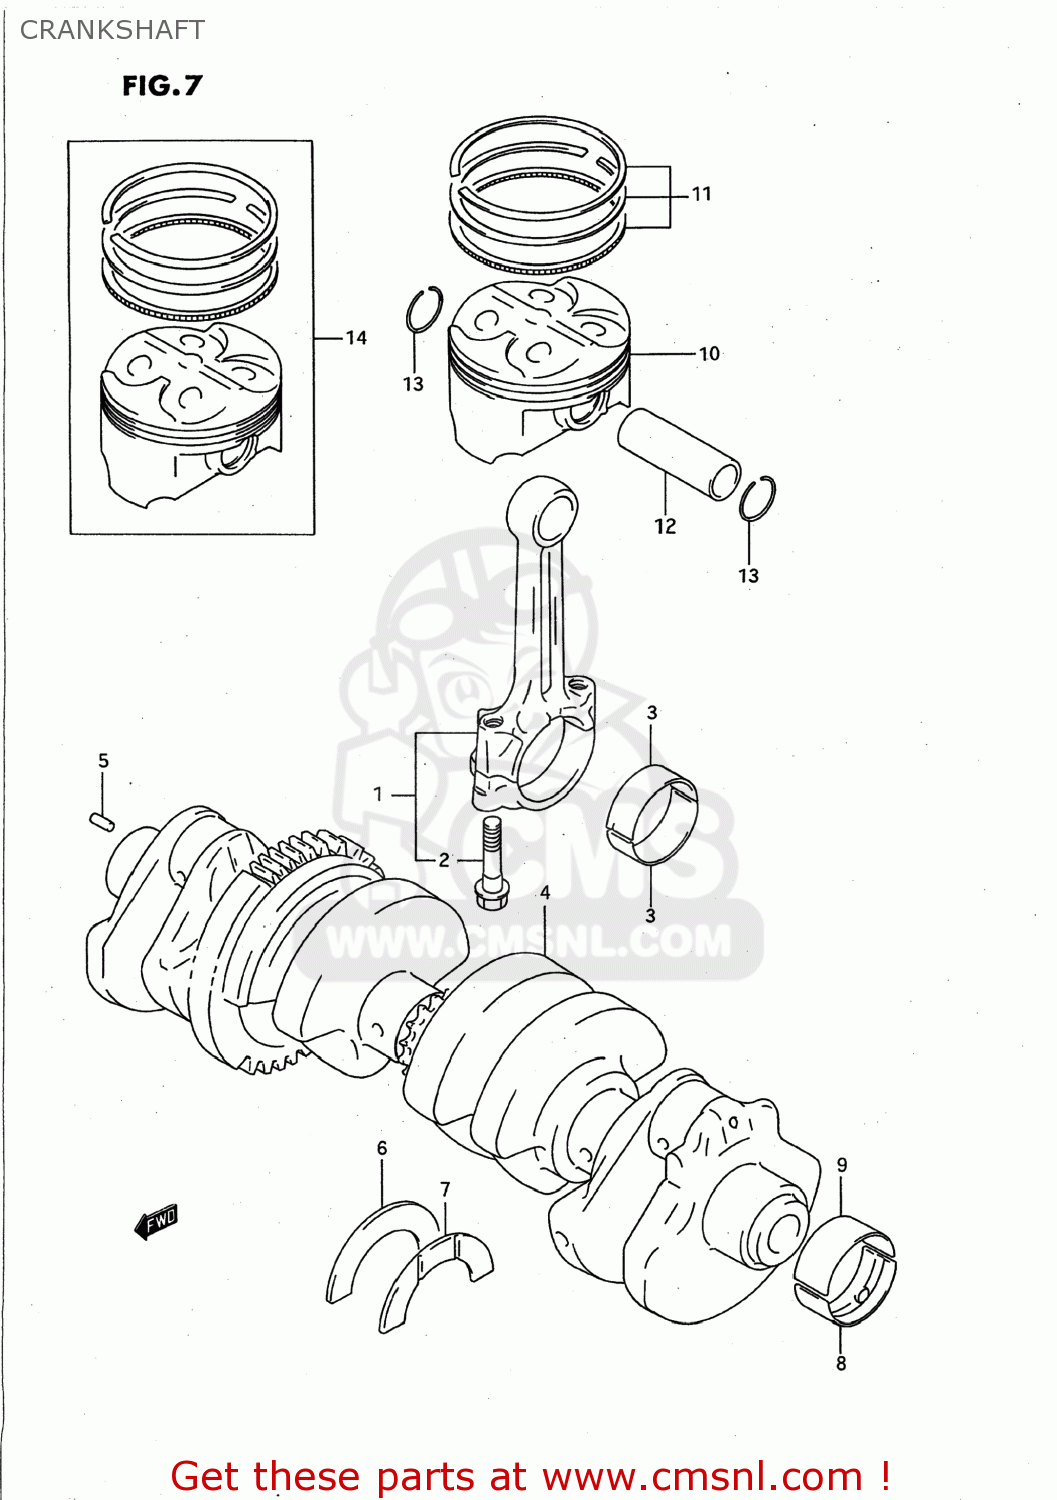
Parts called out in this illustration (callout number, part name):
1	ROD ASSEMBLY,CONNECTING
2	BOLT,CONNECTING ROD
3	BEARING,CRANK PIN
4	CRANKSHAFT SET
5	PIN
6	BEARING,CRANK THRUST(GREEN)
7	BEARING,CRANK THRUST(RED)
8	BEARING,CRANKSHAFT(GREEN)
9	BEARING,CRANKSHAFT(GREEN)
10	PISTON (70.00MM)
11	RING SET,PISTON
12	PIN,PISTON
13	CIRCLIP
14	PISTON SET(OS:0.5)
